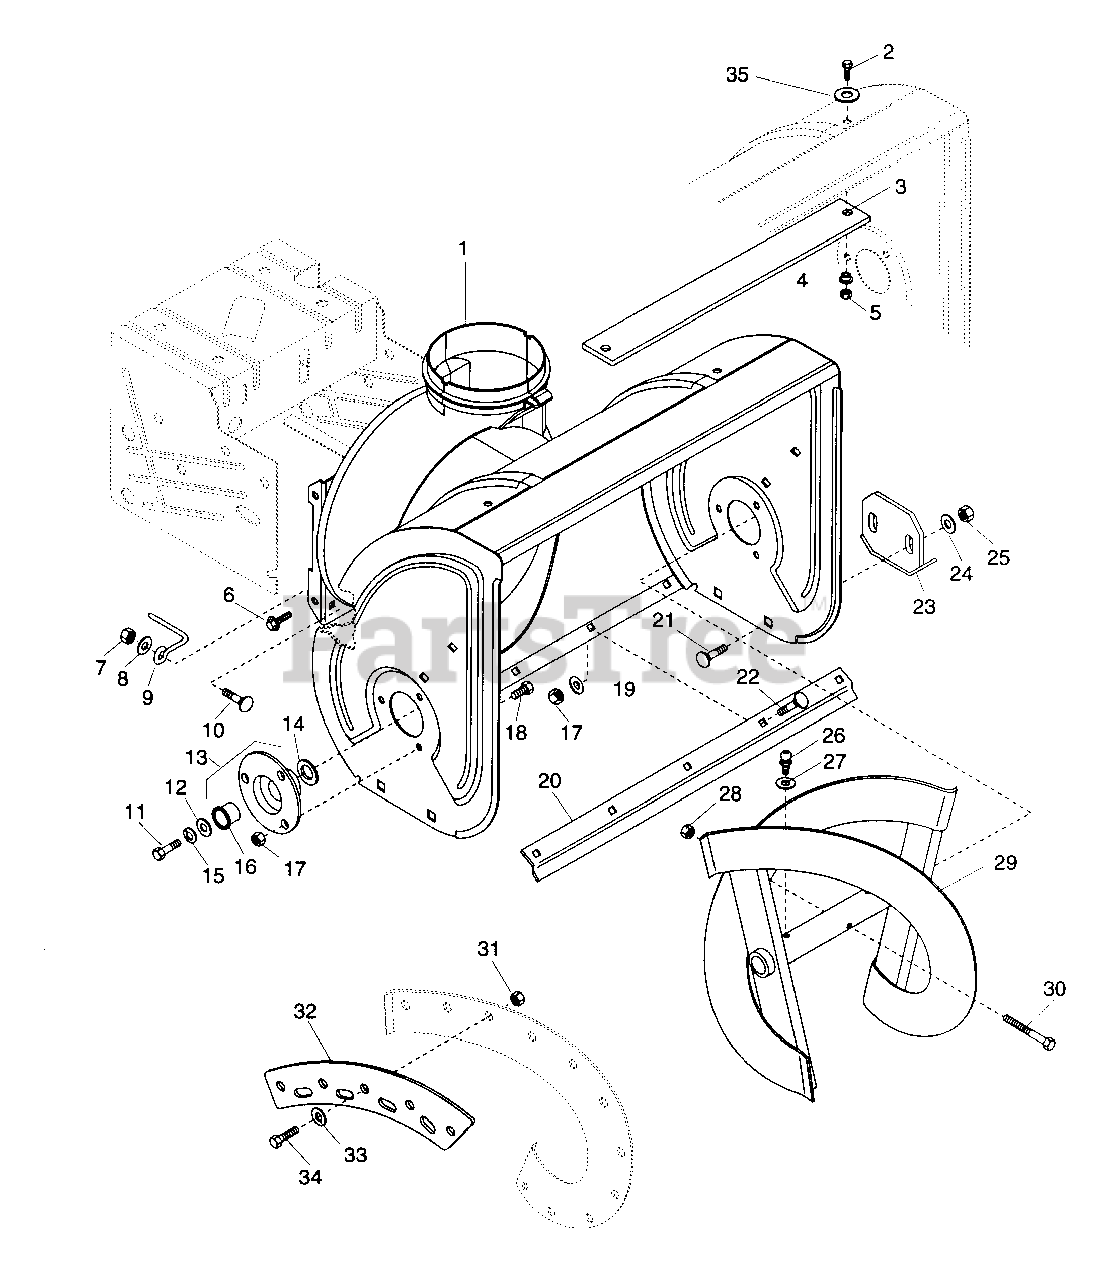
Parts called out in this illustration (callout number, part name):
1	AUGER/IMPELLER HOUSING 20" ST2
1	AUGER/IMPELLER HOUSING 24"
2	BLT-HEX .31-18X1.25 PL GR5
3	WEIGHT-AUGER/IMPELLER HSG
4	BSHG-FLG .325X.500X.70X.875
5	NUT-LK .312-18 GR A PL
6	SCR-TAP .312-18X.50 HWH PL TR
7	NUT-LK-NYL.312-18 PL
8	WSHR-FL-STL .328X.875X.062 PL
9	BELT FINGER
10	BLT-RDHDSQNK.31-18X.75GR5SHTPL
11	BLT-HEX .31-18X.63 PL GR 2
12	WSHR-FL-STL .344X1.375X.075 PL
13	BEARING FLANGE ASSEMBLY
14	WSHR-FL-STL.812X1.500X.139
15	WSHR-LK .312X.097 PL HVY
16	BSHG-FLG .750X1.000X.625X1.250
17	NUT-LK-FLG .250-20 PL
18	BLT-SERNK SL .25-20X.50 PL
19	WSHR-FL-STL.281X.62X.065 PL
20	SCRAPER BLADE
21	BLT-RDHDSQNK .38-16X.75 SHT PL
22	BLT-RDHDSQNK .25-20X.50
22	BLT-RDHDSQNK .25-20X.50 SHT PL
23	RUNNER
24	WSHR-FL-STL .38X.875X.083 PL
25	NUT-LK-CTR .375-16 GR A PL
26	FTG-LUBE .25-28X.256 YWZC
27	WSHR-FL-STL .265X.500X.087 PL
28	NUT-LK-CTR .250-20 PL
29	RAKE, RIGHT-24"(.75ID X 10.88)
29	RAKE, LEFT-24(.75ID X 10.88OD)
29	RAKE, RIGHT-20(.75ID X 10.5OD)
29	RAKE, LEFT-20"(.75ID X 10.5OD)
30	SHEAR BOLT WITH NUT
31	NUT-LK TOP 10-24 PL
32	RAKE EDGE W/HARDWARE
33	WSHR-FL-STL .194X.492X.047 PL
34	SCR-MCH 10-24X.63 HEX PL
35	WSHR-FL-STL .406X1.000X.188 PL
